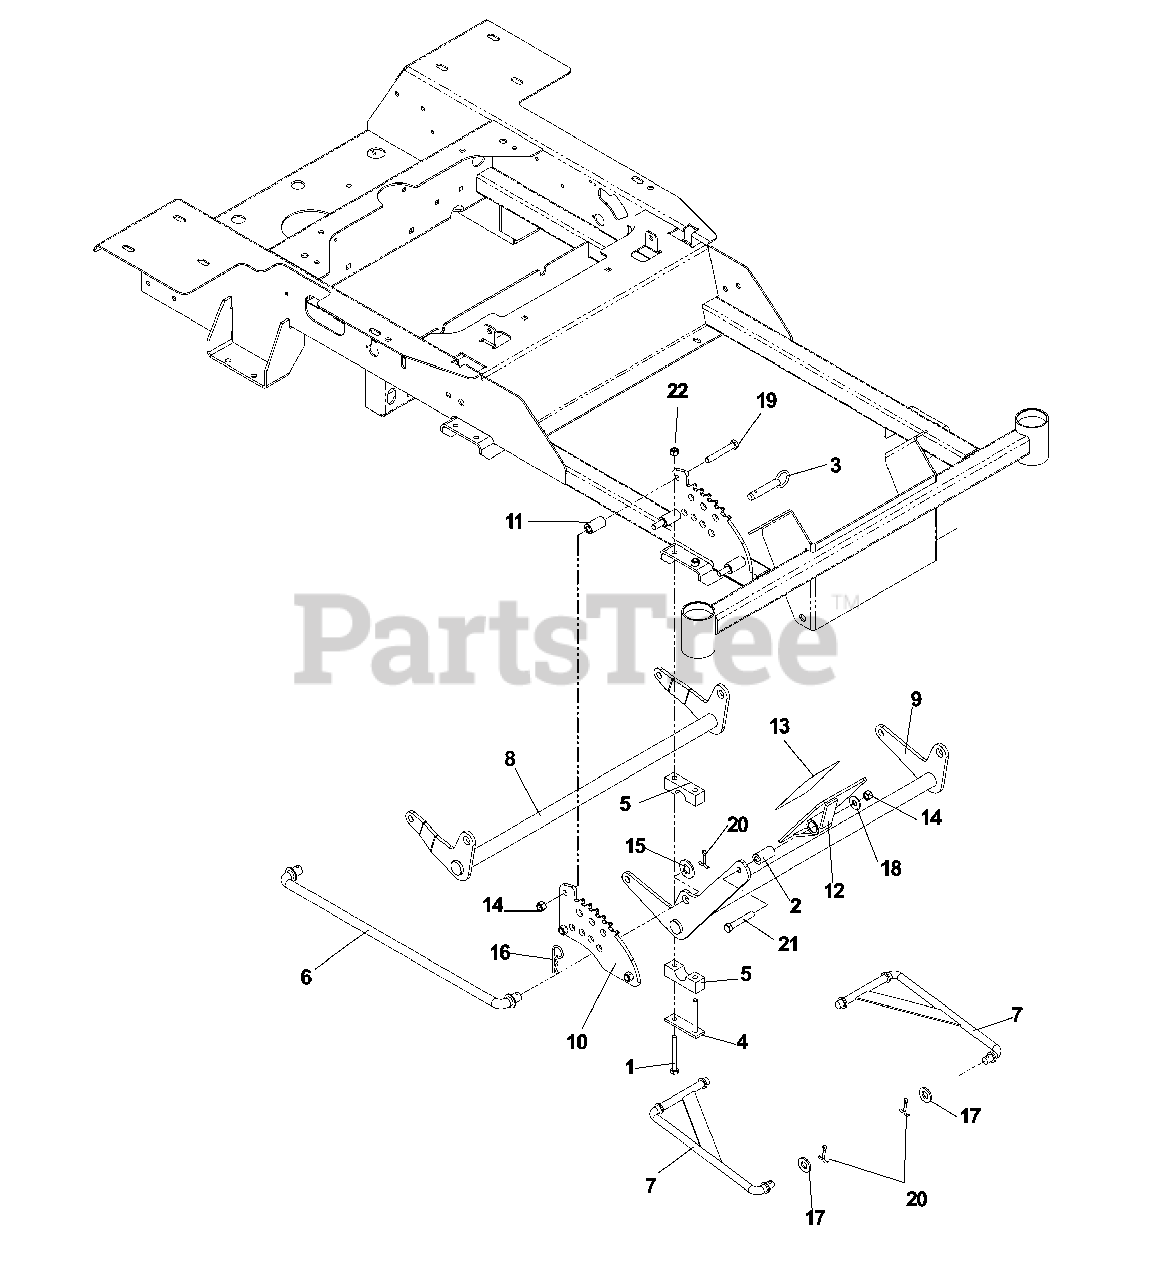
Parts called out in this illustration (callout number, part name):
1	HCS 5/16C X 2-3/4
2	BUSHING, SLEEVE
3	HITCH PIN
4	REINFORCEMENT BAR
5	PILLOW BLOCK
6	CROSS LINK
7	STRUT LINKAGE
8	LIFT SHAFT, REAR
9	LIFT SHAFT, FRONT
10	PLATE, HEIGHT, OUTER
12	PEDAL, FOOT, WELDMENT
13	FOOT PAD
14	NUT 3/8-16 NYLOC
15	WASHER 5/8 FLAT
16	HAIRPIN #4
17	WASHER 1/2" FLAT
18	WASHER 3/8 FLAT
19	HCS 3/8C X 2 1/2
20	COTTER PIN
21	HCS 3/8C X 2 1/4
22	NUT 5/16 NYLOC
